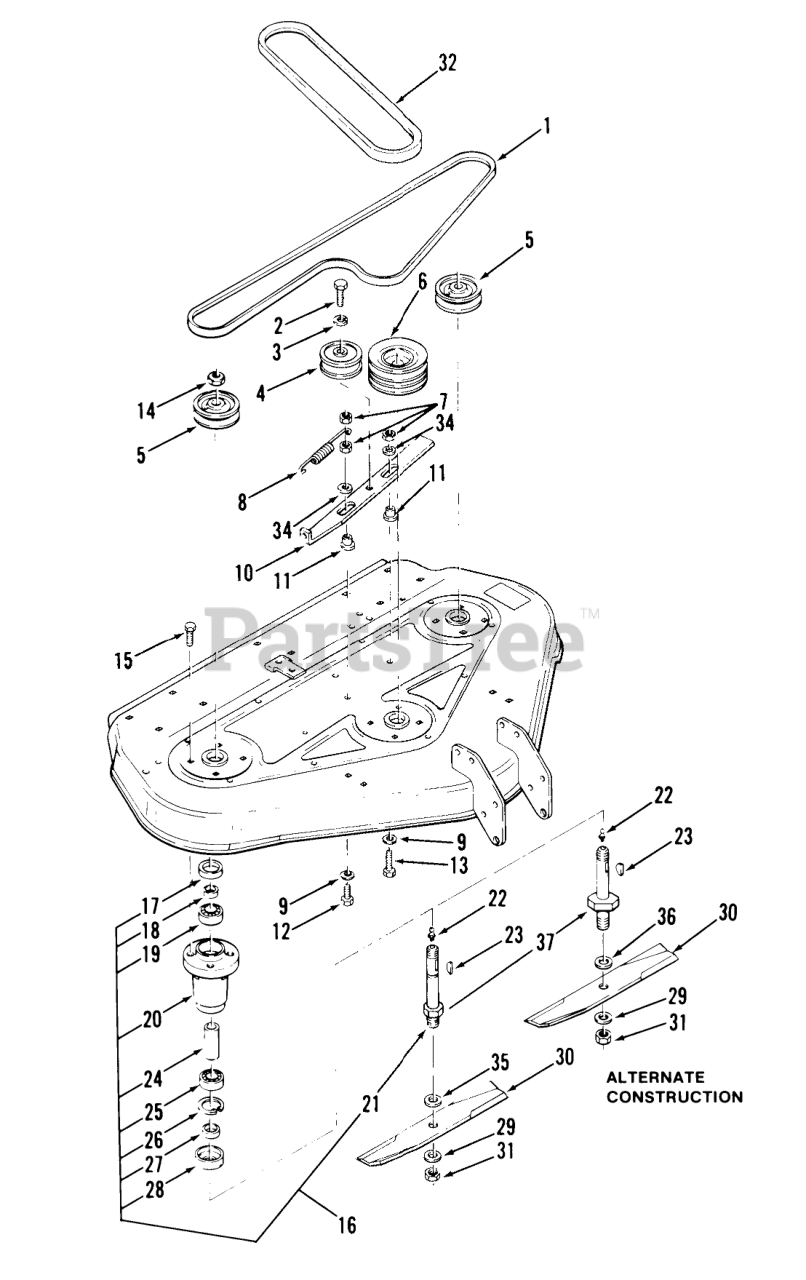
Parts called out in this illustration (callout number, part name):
1	V-BELT
2	BOLT HEX SPECIAL
3	LOCKWASHER
4	Idler Pulley
5	PULLEY-BLADE DRIVE
6	PULLEY-MOWER
7	NUT
8	SPRING-EXTENSION
9	WASHER
10	BAR-IDLER SUPPORT
11	SPACER-BUSHING
12	Bolt
13	Bolt
14	Nut
15	Bolt
16	Spindle Assembly
18	SPACER-SEAL
19	BEARING-BALL
20	HOUSING-SPINDLE
21	SPINDLE SHAFT ASM
22	Grease Fitting
23	Hi-Pro Key 3/16 x 5/8
24	SPACER
25	BEARING-BALL
26	Ring-Snap
27	SPACER-BLADE
28	CUP-SPINDLE
29	SpeciaI Washer
30	S/A BLADE KIT
31	Nut
32	V-BELT
34	WASHER
35	Washer
36	SpeciaI Washer
37	Spindle Shaft
